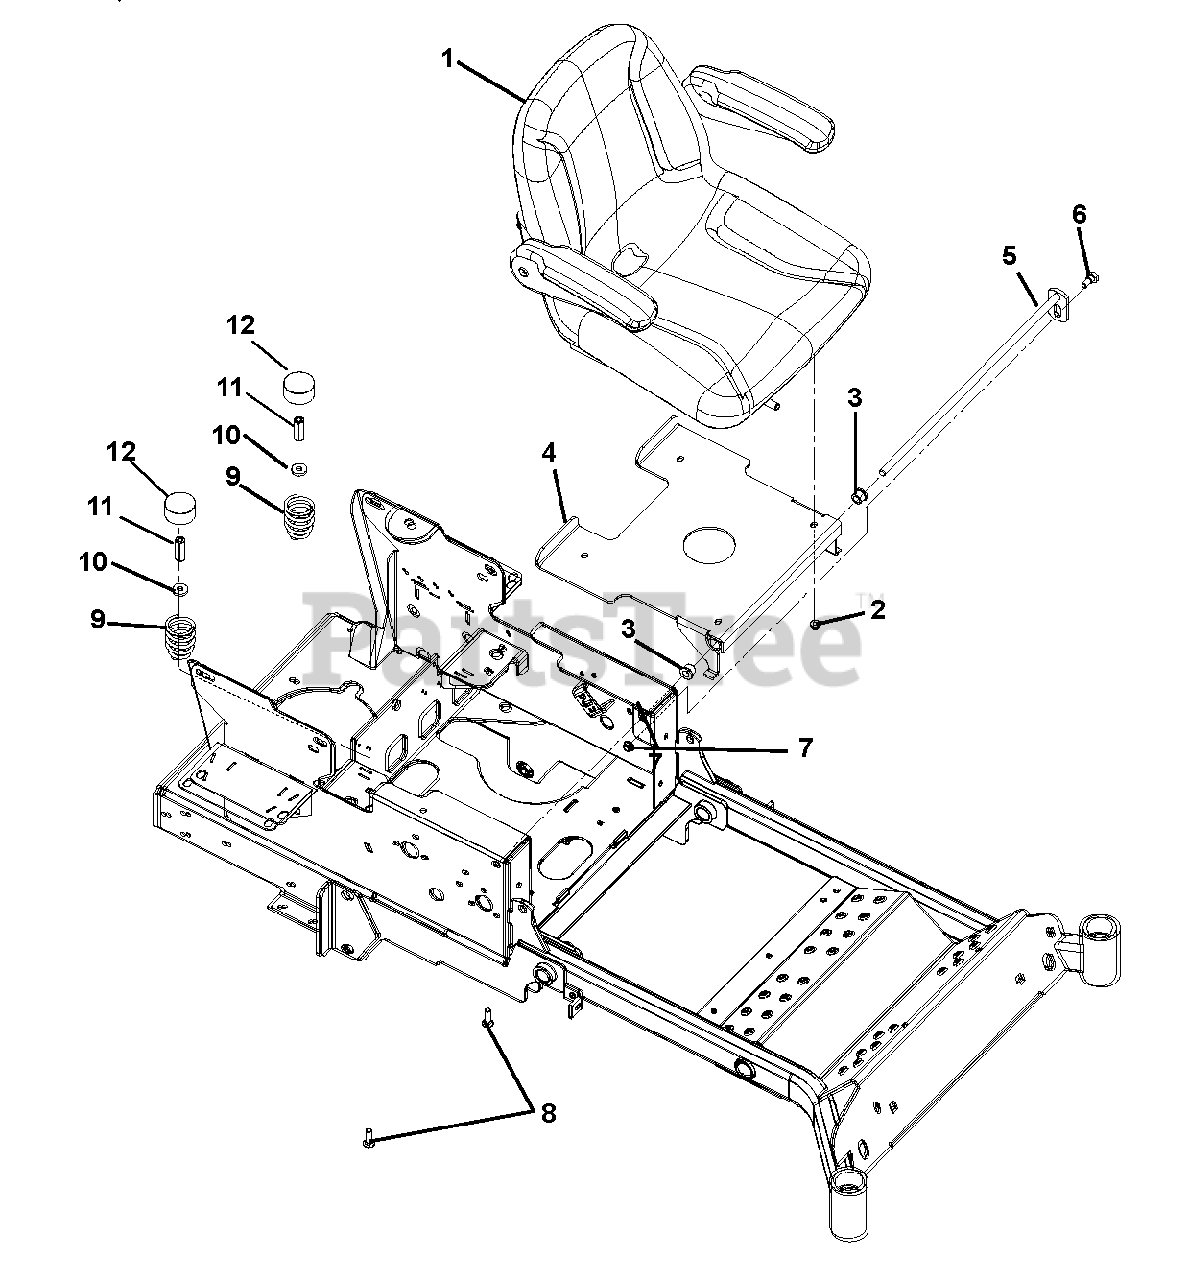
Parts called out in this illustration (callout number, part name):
1	Assembly, Seat with Armrests
2	Nut, Nyloc Flange 5/16-18
3	Bushing, Flange .515 x .750 x .745 x 1.00
4	Weldment, Seat Plate
5	Weldment, Seat Shaft
6	Bolt, Shoulder EP .38-16 x .30 Hex
7	Nut, .38-16 Nyloc Flange
8	Bolt, Round Head Square Neck .38-16 x 1.25 Grade 5
9	Spring, Seat
10	Washer, Flat-Steel .406 x 1.00 x .188
11	Nut, Coupling .375-16 x 1.75
